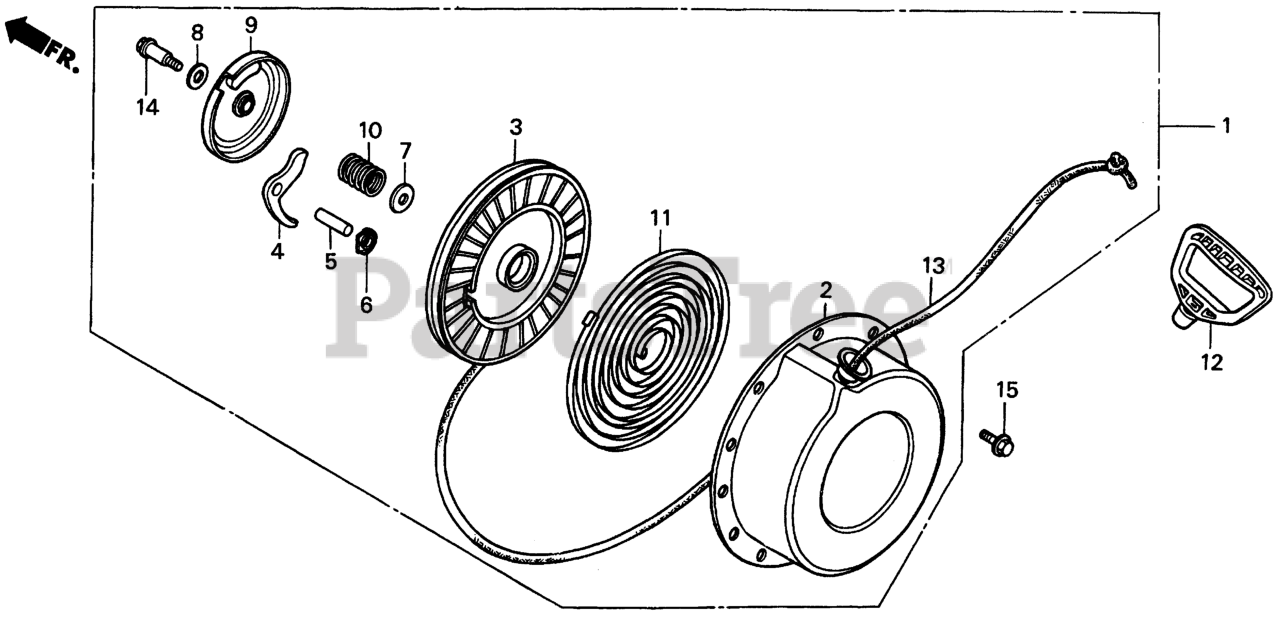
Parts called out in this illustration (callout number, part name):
1	STARTER ASSY., RECOIL *R8* (BRIGHT RED)
2	CASE, STARTER *R8* (BRIGHT RED)
3	REEL, STARTER (NOT AVAILABLE)
4	RATCHET, STARTER
5	SHAFT, RATCHET
6	PLATE, GUIDE
7	PLATE A, FRICTION
8	PLATE B, FRICTION
9	COVER, REEL STARTER
10	SPRING, FRICTION
11	SPRING, RETURN
12	GRIP, STARTER
13	ROPE, STARTER (#5X55") (N/A: USE P/N 08550-ZG921-11)
14	BOLT, REEL COVER
15	BOLT, FLANGE (6X8)
